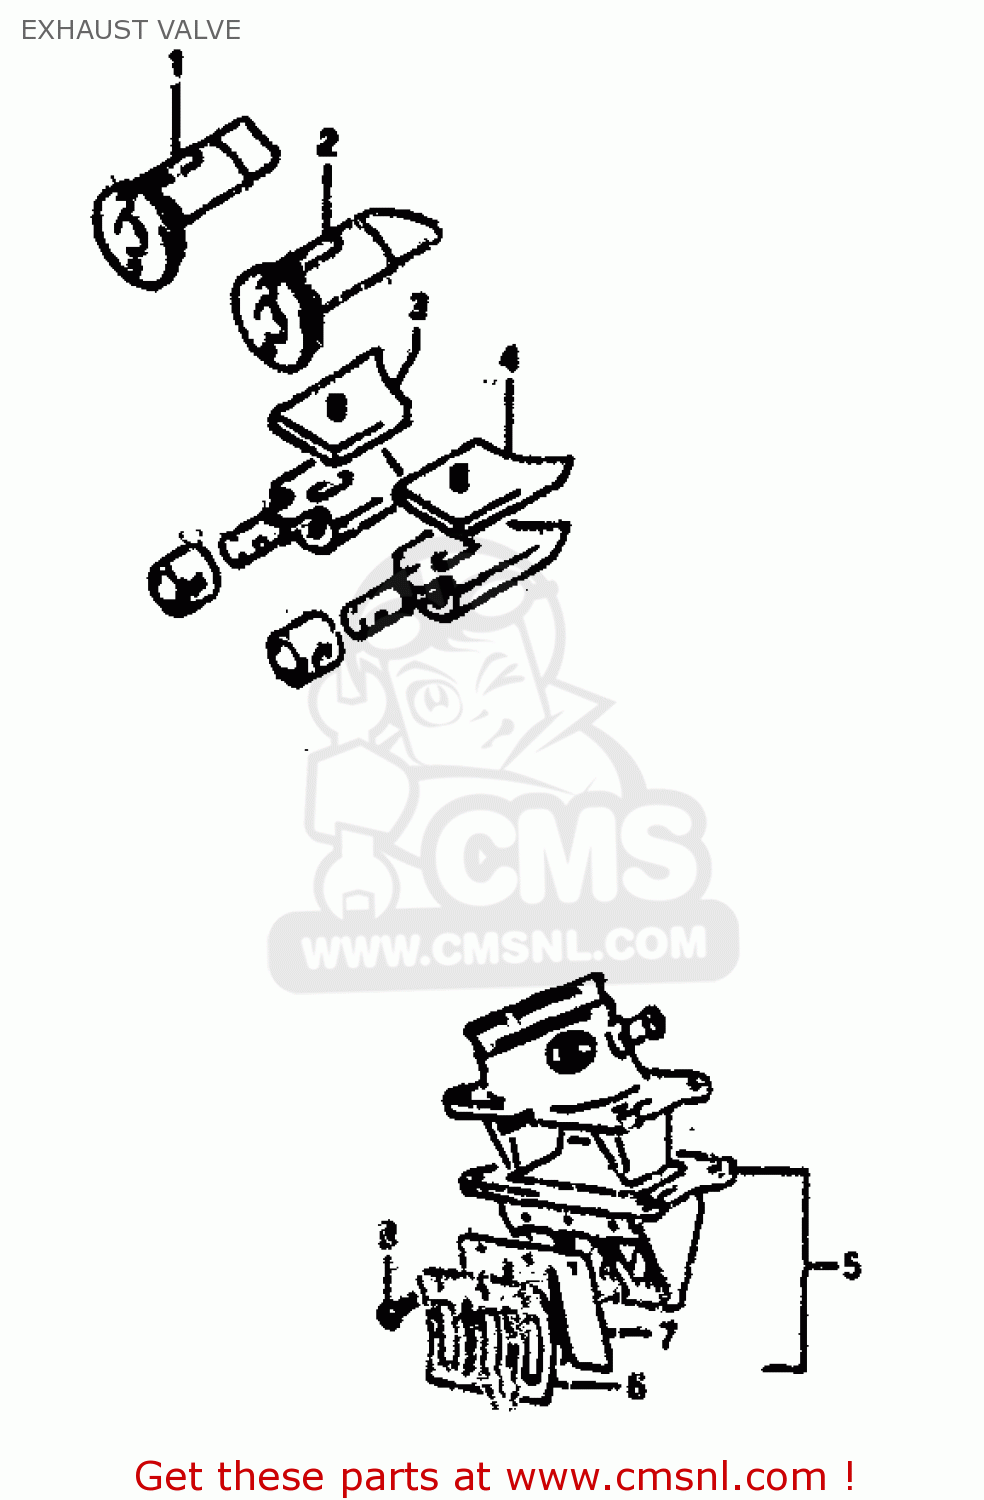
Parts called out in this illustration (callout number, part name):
1	GUIDE, EXHAUST VALVE RH
2	GUIDE, EXHAUST VALVE LH
3	VALVE, EXHAUST NO.2,RH
4	VALVE, EXHAUST NO.2,LH
5	VALVE ASSY, REED
6	STOPPER, REED VALVE
7	VALVE,REED
8	SCREW
